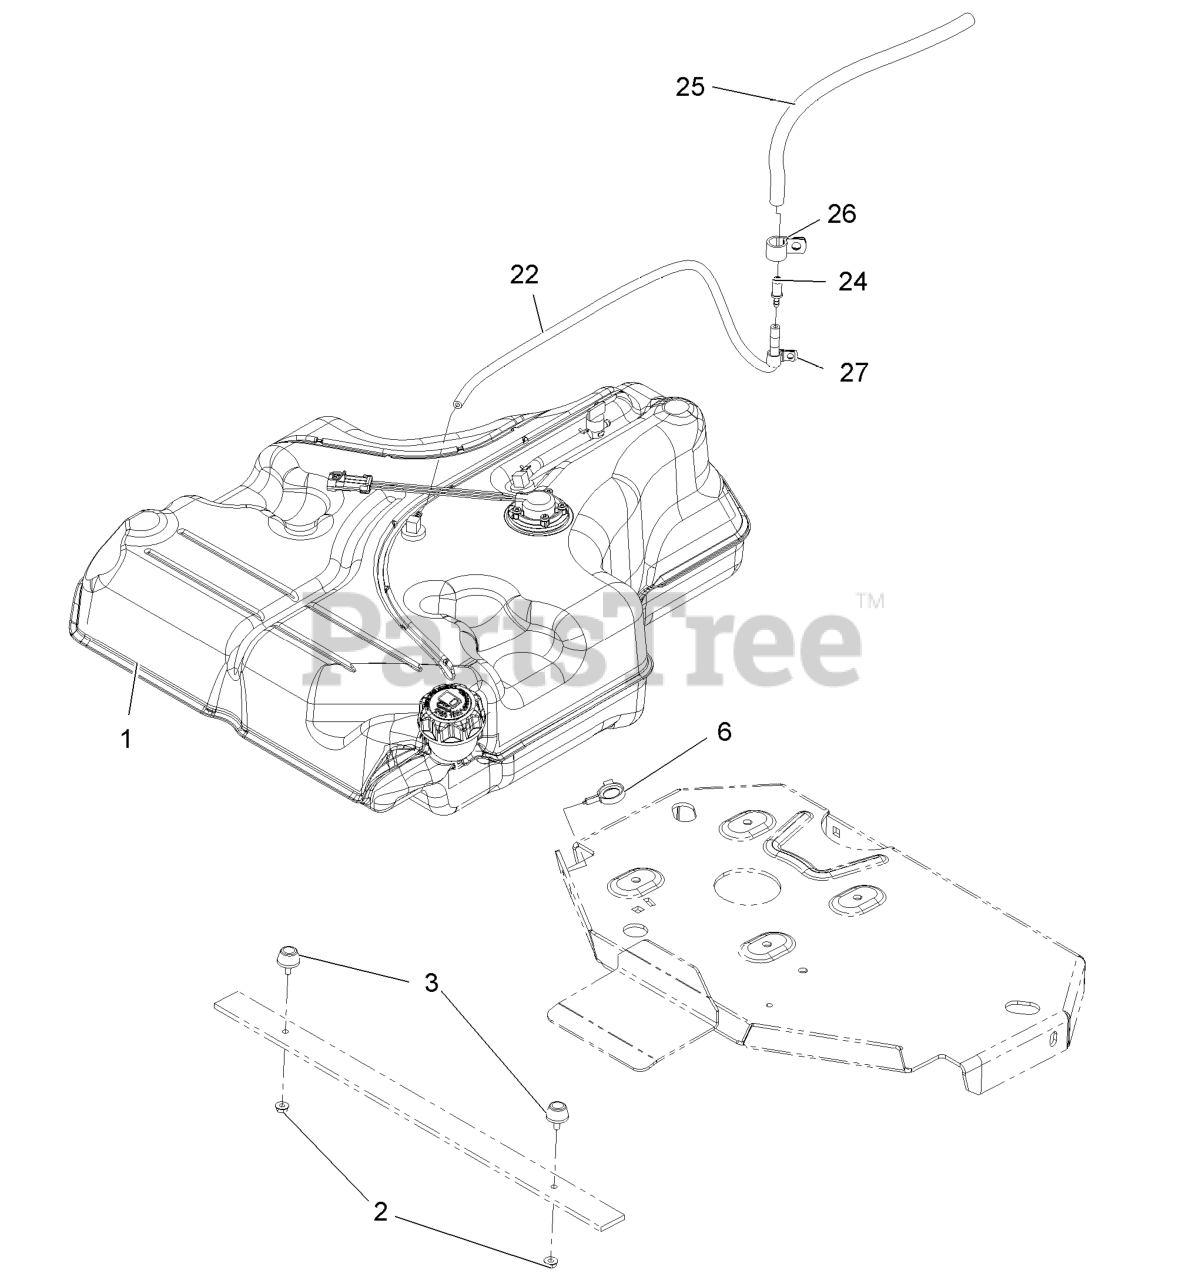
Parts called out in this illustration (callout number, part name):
3	BUMPER-RUBBER
6	CLAMP-HOSE
22	HOSE-FUEL
24	FITTING-STRAIGHT
25	HOSE-FUEL
26	CLIP-LOOM
27	CLIP-LOOM
